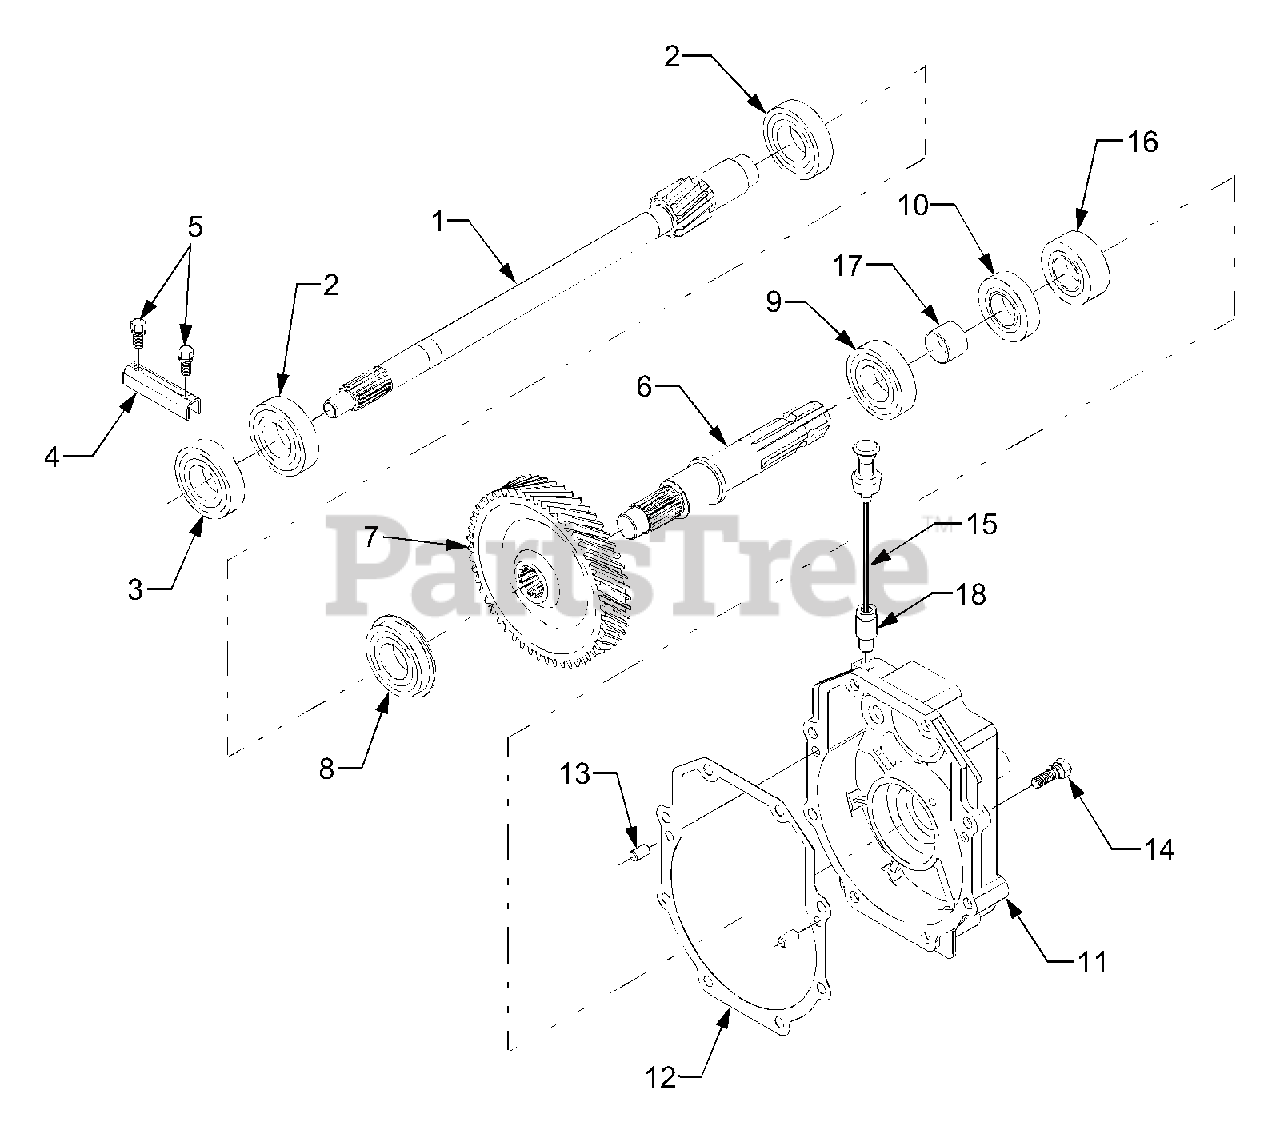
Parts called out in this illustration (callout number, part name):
1	Shaft, PTO Drive
2	Bearing, Ball
3	Bearing, Ball
4	Stopper, Bearing
6	Shaft, PTO
8	Bearing, Ball
9	Bearing, Ball
18	Guide, Oil Gauge
